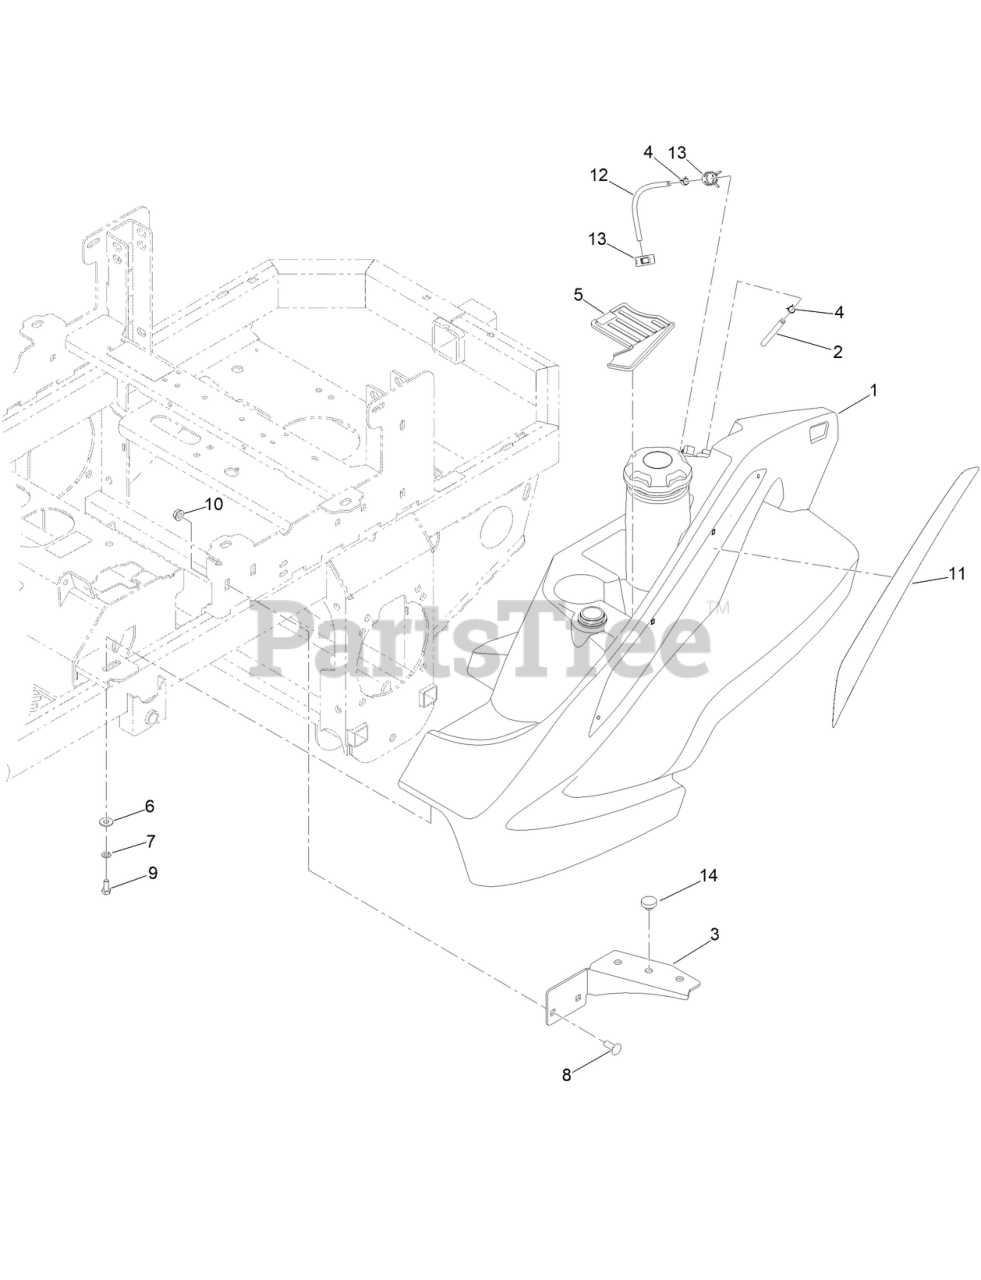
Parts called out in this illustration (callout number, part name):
1	MWR GASOLINE FUEL TANK ASSY
2	MWR FUEL TANK BLACK 3/16IN VENT TUBE 1FT
3	RT/SRT GAS TANK SUPPORT PAINTED
4	1/2IN (#8) HOSE CLAMP
5	RUBBER TANK STORAGE COMPARTMENT INSERT
6	WASHER-FLAT
7	WASHER-LOCK
8	3/8-16 X 1 CARRIAGE BOLT YZ GR.8
9	SCREW-HH
10	3/8-16 HEX FLANGE NUT W/SERR ZINC YELLOW
11	DECAL-TANK
12	1/4IN SAE J30R7 BULK HOSE 1FT
13	19MM HOSE CLAMP
14	PUSH-IN RUBBER BUMPER MWR FLOOR
